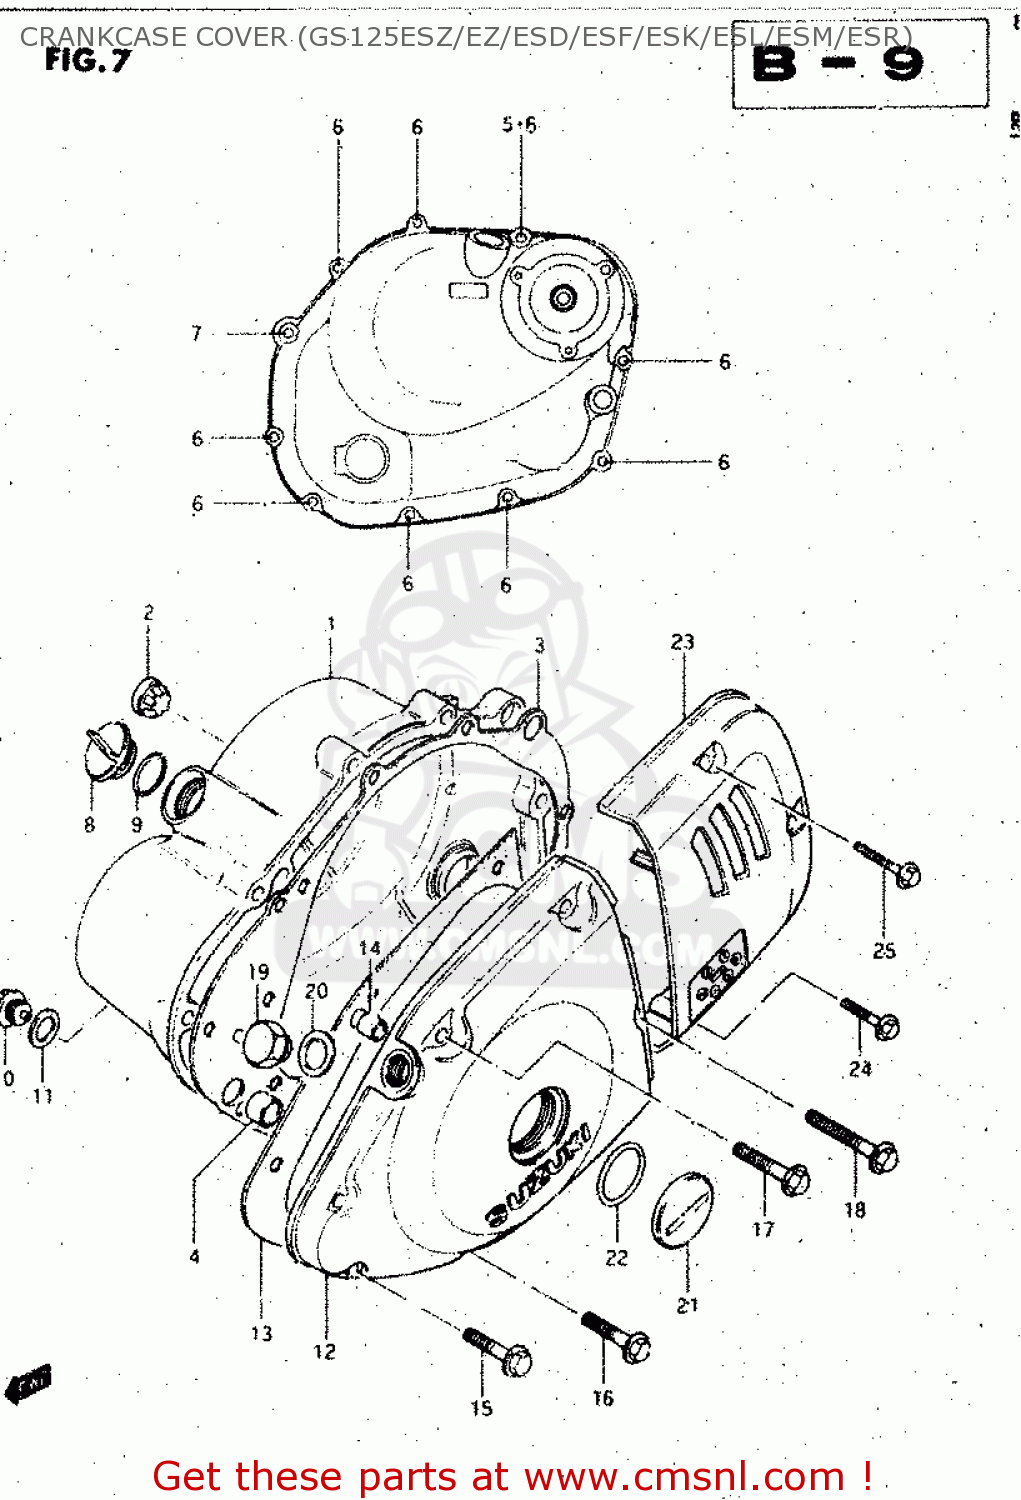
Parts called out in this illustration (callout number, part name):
1	COVER,CLUTCH
2	LENS,OIL LEVEL CHECK
3	GASKET,CLUTCH COVER (NAS)
4	PIN
5	GASKET(5.8X13X1.2) (NAS)
6	BOLT
7	BOLT
8	PLUG
9	O RING(D:3.1,ID:16.8)
10	PLUG(14X12)
11	GASKET(13.8X18.8X4.8) (NAS)
12	COVER,MAGNETO
13	GASKET,MAGNETO COVER (NAS)
14	PIN
15	BOLT
16	BOLT
17	BOLT
18	BOLT
19	PLUG,12X9
20	GASKET(12.1X16.2X3.7) (NAS)
21	PLUG(26X9)
22	O RING(D:3.1,ID:22.7)
23	COVER,ENGINE SPROCKET
24	BOLT
25	BOLT
